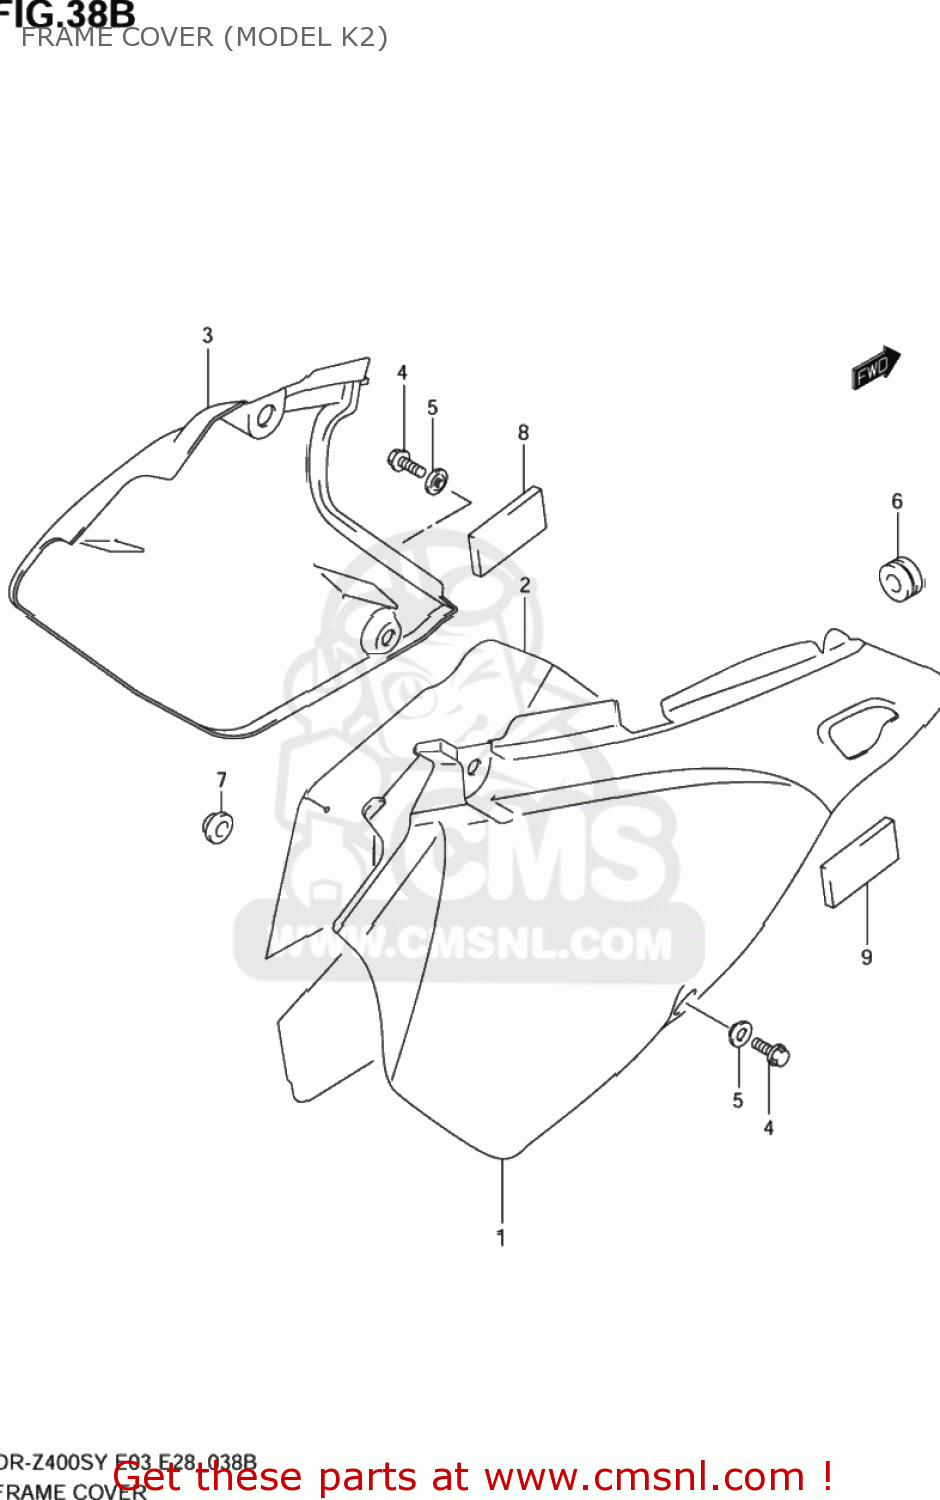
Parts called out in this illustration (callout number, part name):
1	COVER,FRAME,R(YELLOW)
2	SHIELD,FRAME COVER,R
3	COVER,FRAME,L(YELLOW)
4	BOLT
5	WASHER
6	CUSHION
7	CUSHION
8	CUSHION,FRAME COVER,L
9	CUSHION
